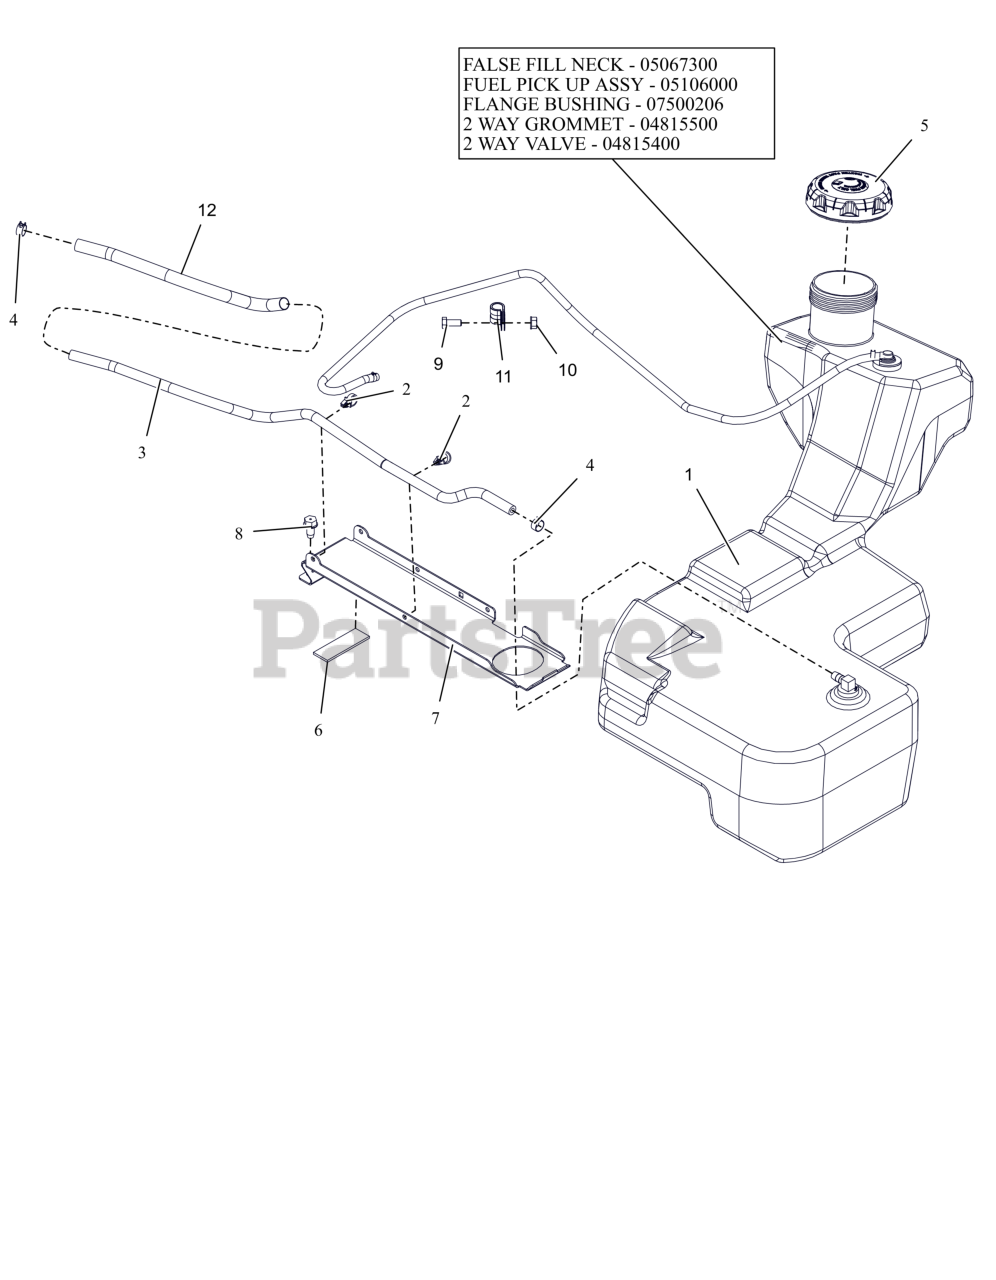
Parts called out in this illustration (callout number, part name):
1	ASM, FUEL TANK-HD
1	INSERT, FUEL NECK FALSE FILL
1	ASM, HD FUEL PICK-UP
1	BSHG-FLG .375X1.062X.625 NITR
1	GROMMET, 2-WAY
1	VALVE, 2-WAY
2	ROUTING CLIP (1/2" ID)
3	HOSE, .25 LOW-PERM BULK GAS
4	CLAMP, FUEL LINE
5	CAP, FUEL VENTIN AUTOLOCK
6	PAD,RBR 1.0"X3.0" W/ADHESIVE
7	BRKT, FUEL TANK HOLD DOWN
8	SCR,TAP .375-16X.75 HWH TR ZCC
9	BLT,HEX .31-18X.75 G5 ZCC
10	NUT,LK-CTR-FLG .31-18 GF ZCC
11	CLAMP, CUSHIONED STEEL
12	SLEEVE, THERMAL 12"
